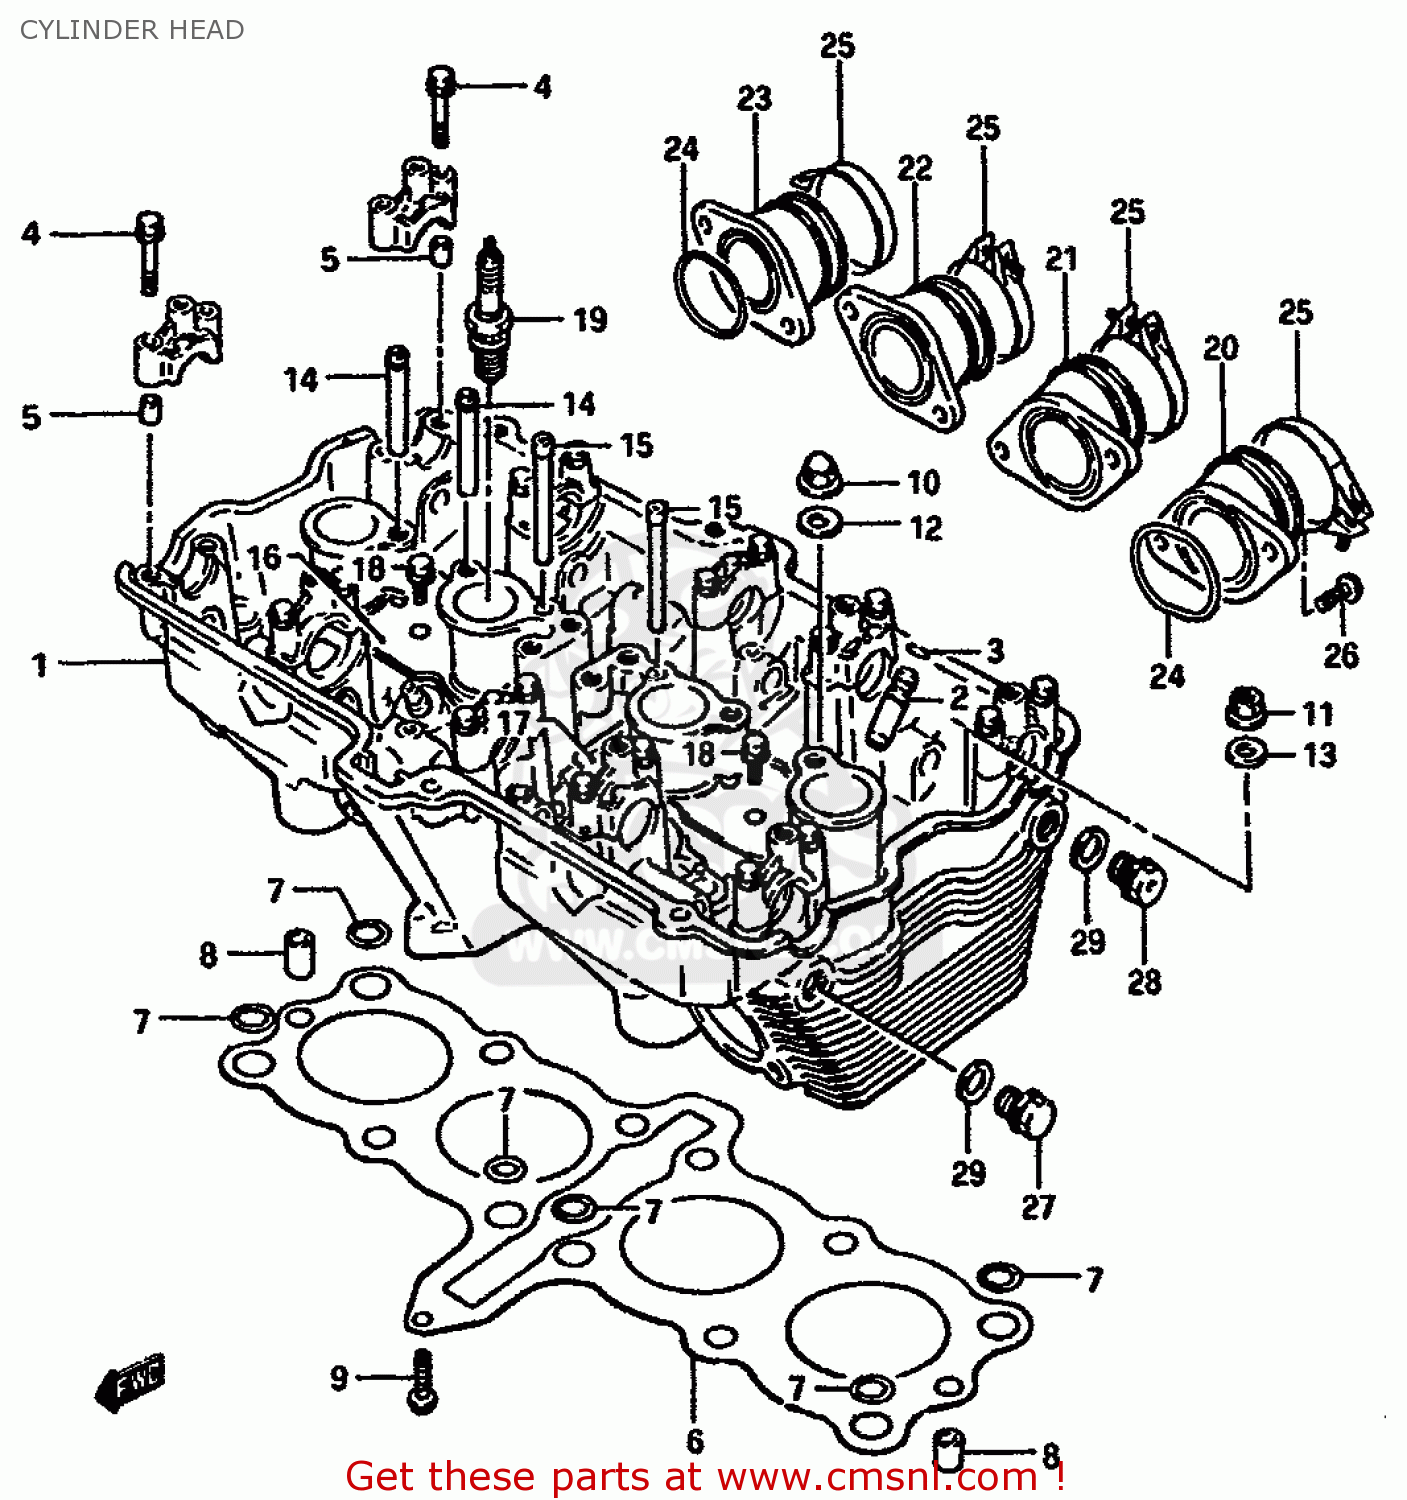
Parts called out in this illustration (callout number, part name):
1	HEAD ASSY, CYLINDER
2	GUIDE,VALVE
3	RING,SNAP
4	BOLT(6X39)
5	PIN(6.2X8X11)
6	GASKET,CYLINDER HEAD (NAS)
7	O RING(D:2.6,ID:12.1)
8	PIN
9	BOLT
10	NUT
11	NUT
12	GASKET(10.2X20X2).3 (NAS)
13	WASHER (10.5X22X2.3)
14	PIPE,OIL NO.1
15	PIPE,OIL NO.3
16	PLATE,OIL PIPE,R
17	PLATE,OIL PIPE,L
18	BOLT
19	SPARK PLUG D9EA
20	PIPE,INTAKE
21	PIPE,INTAKE
22	NET,INTAKE
23	PIPE,INTAKE
24	O RING(D:2.4,ID:39.7)
25	CLAMP
26	SCREW
27	PLUG
28	PLUG
29	GASKET(14X19.2X2) (NAS)
